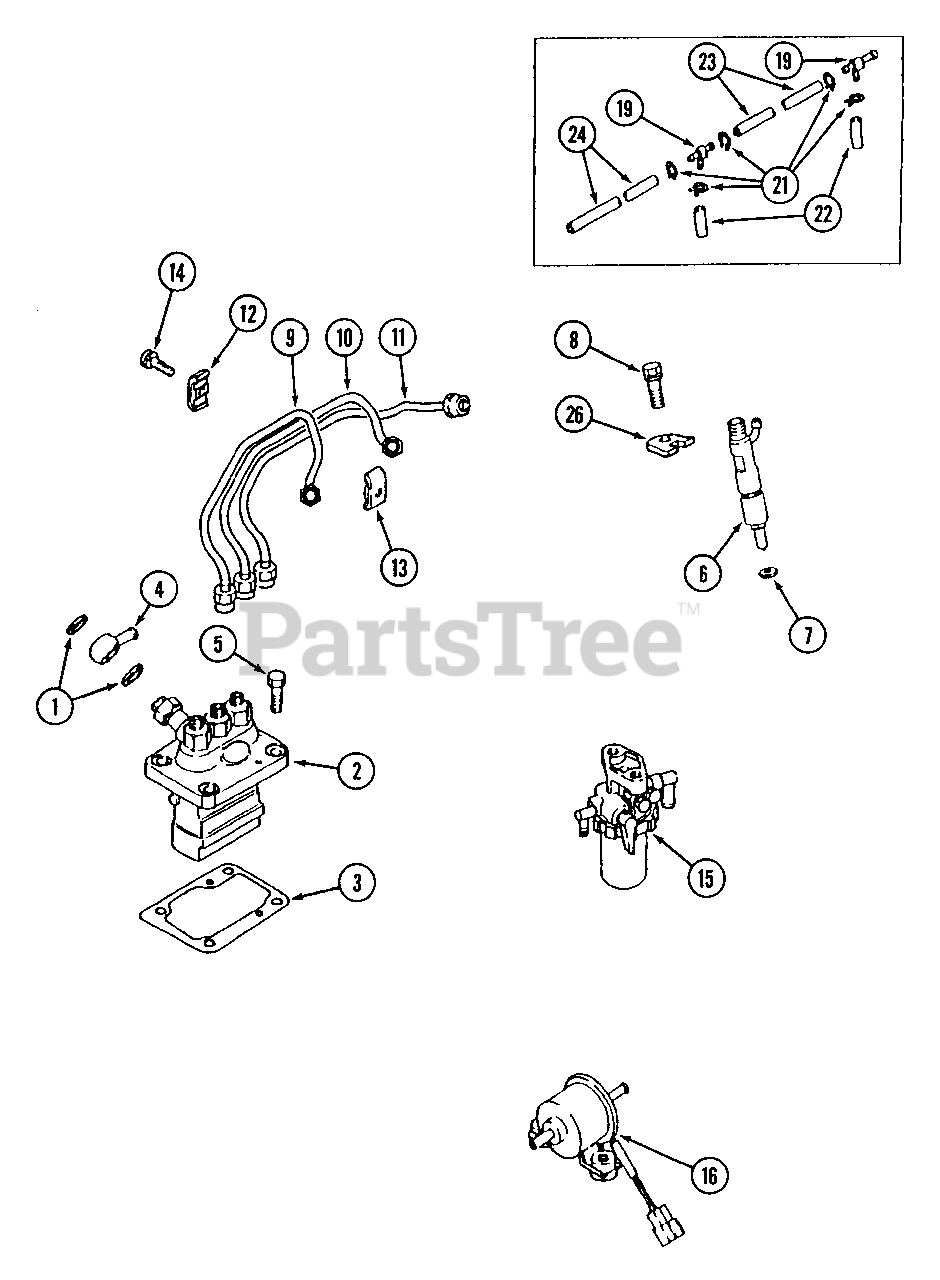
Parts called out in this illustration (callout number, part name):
2	Pump Ass'y., Fuel Injection
3	Shim Set, Adjusting
4	Collar, Union
5	Bolt
6	Nozzle & Holder Ass'y.
7	Gasket, Nozzle Holder
8	Bolt
9	Pipe Ass'y., Fuel Injection No. 1
10	Pipe Ass'y., Fuel Injection No. 2
11	Pipe Ass'y., Fuel Injection No. 3
14	Bolt, w/Washer
15	Filter Ass'y., Fuel
16	Pump Ass'y., Electric, Fuel
21	Clamp, Hose
26	Support Nozzle
